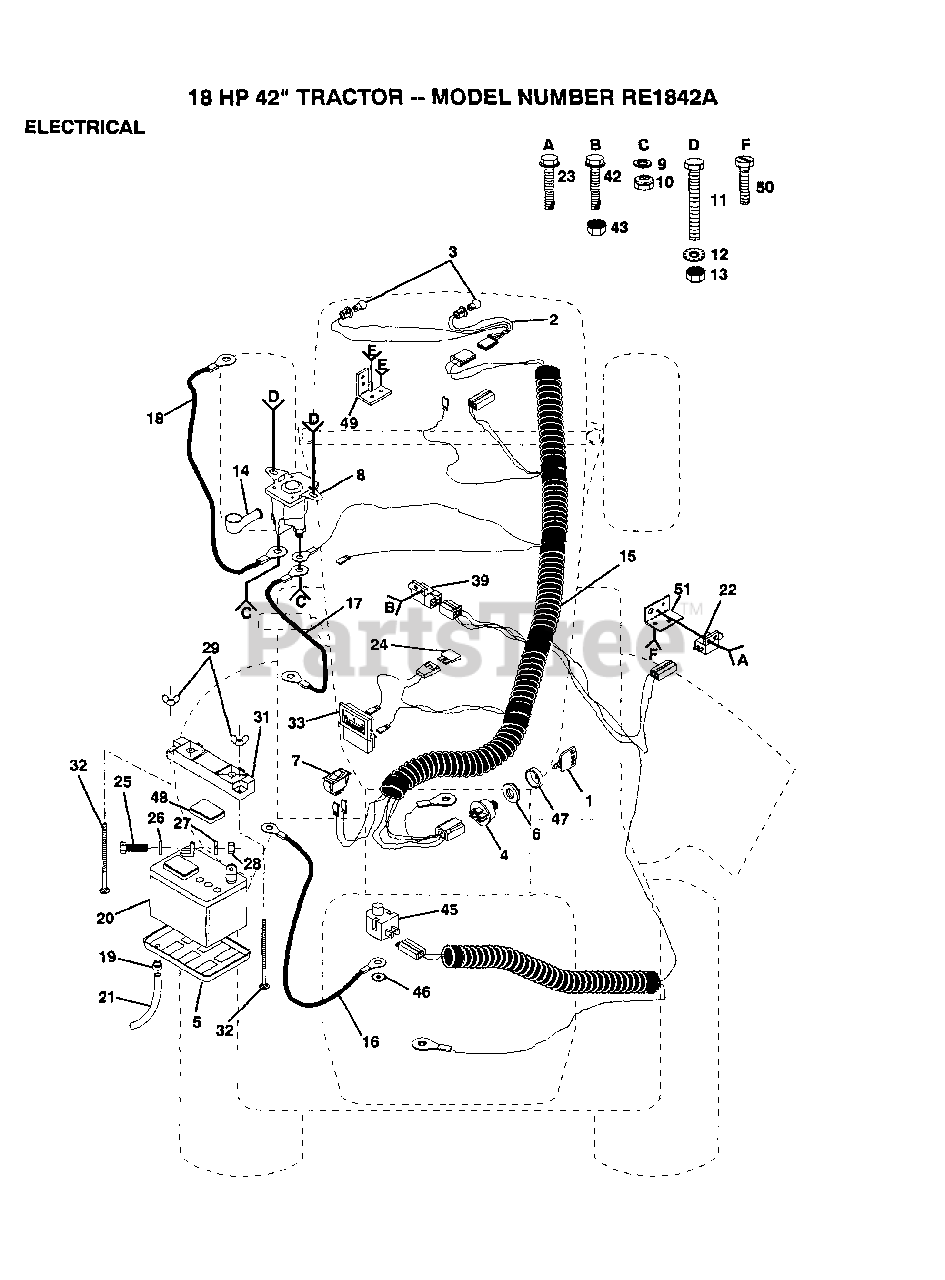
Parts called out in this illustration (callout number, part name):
1	KEY
2	HARNESS T
5	"TRAY T, BATTERY"
6	NUT IGNITION
7	SWITCH LT
10	NUT
11	BOLT
13	NUT
16	"CABLE T, BATTERY"
17	CABLE LT
18	CABLE T
19	HOSE CLAMP T
22	SWITCH-INTER. GT
23	SCREW
24	FUSE HYT
25	BOLT LT
26	WASHER
27	LOCKWASHER
32	BOLT
39	SWITCH INTERLOCKT
42	SCREW
43	"NUT,KEPS"
45	SWITCH SEAT
46	LOCKWASHER
48	"CAP,BATTERY "
49	SWITCH BRACKET
50	SCREW
51	BRACKET LT
